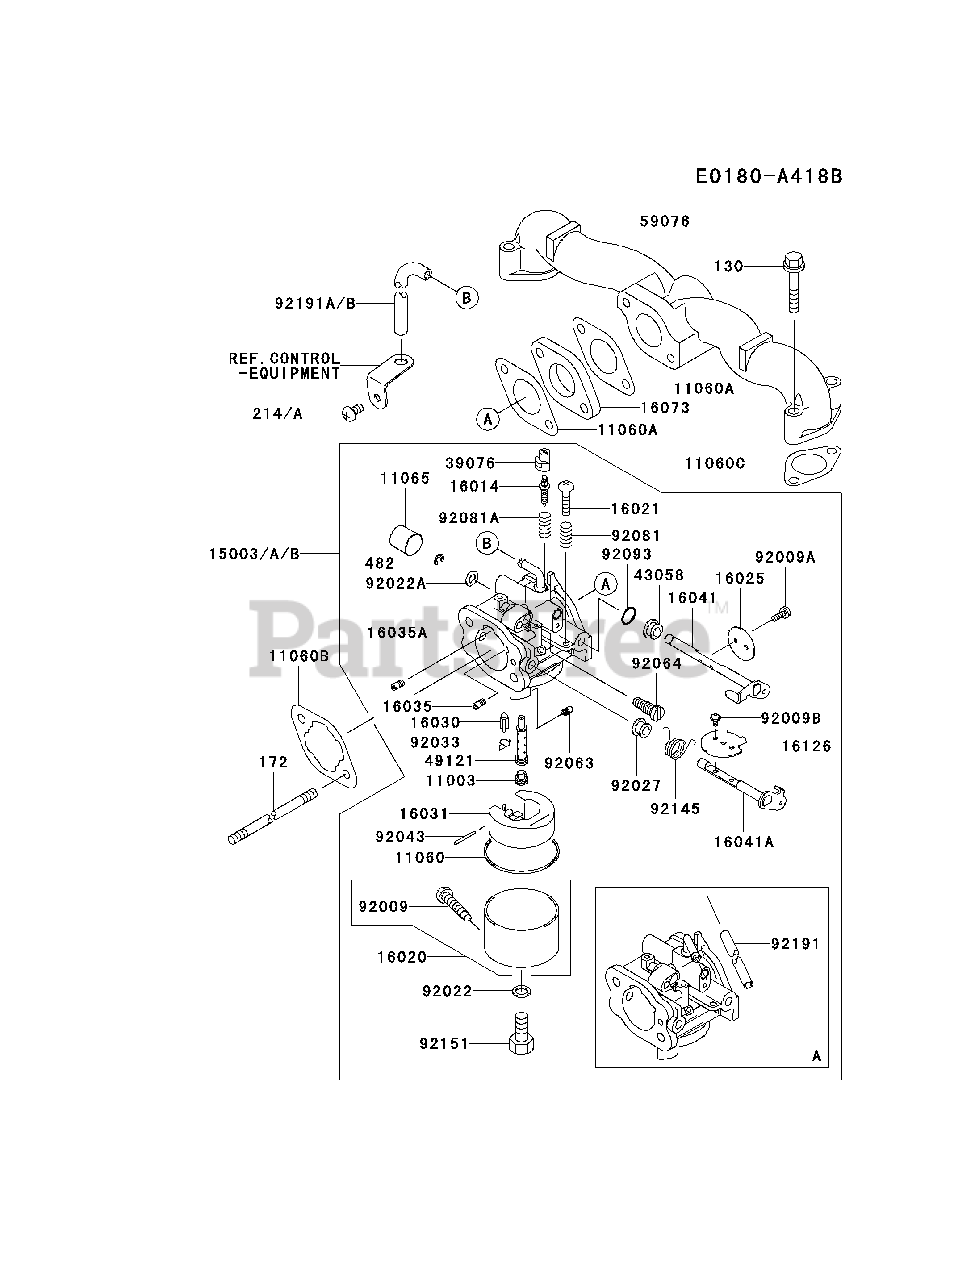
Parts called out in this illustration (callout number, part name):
130	BOLT-FLANGED
172	BOLT-STUD
214	SCREW-PAN+-
482	CIRCLIP-TYPE-E
92191A	TUBE,4.76X7.94X225
